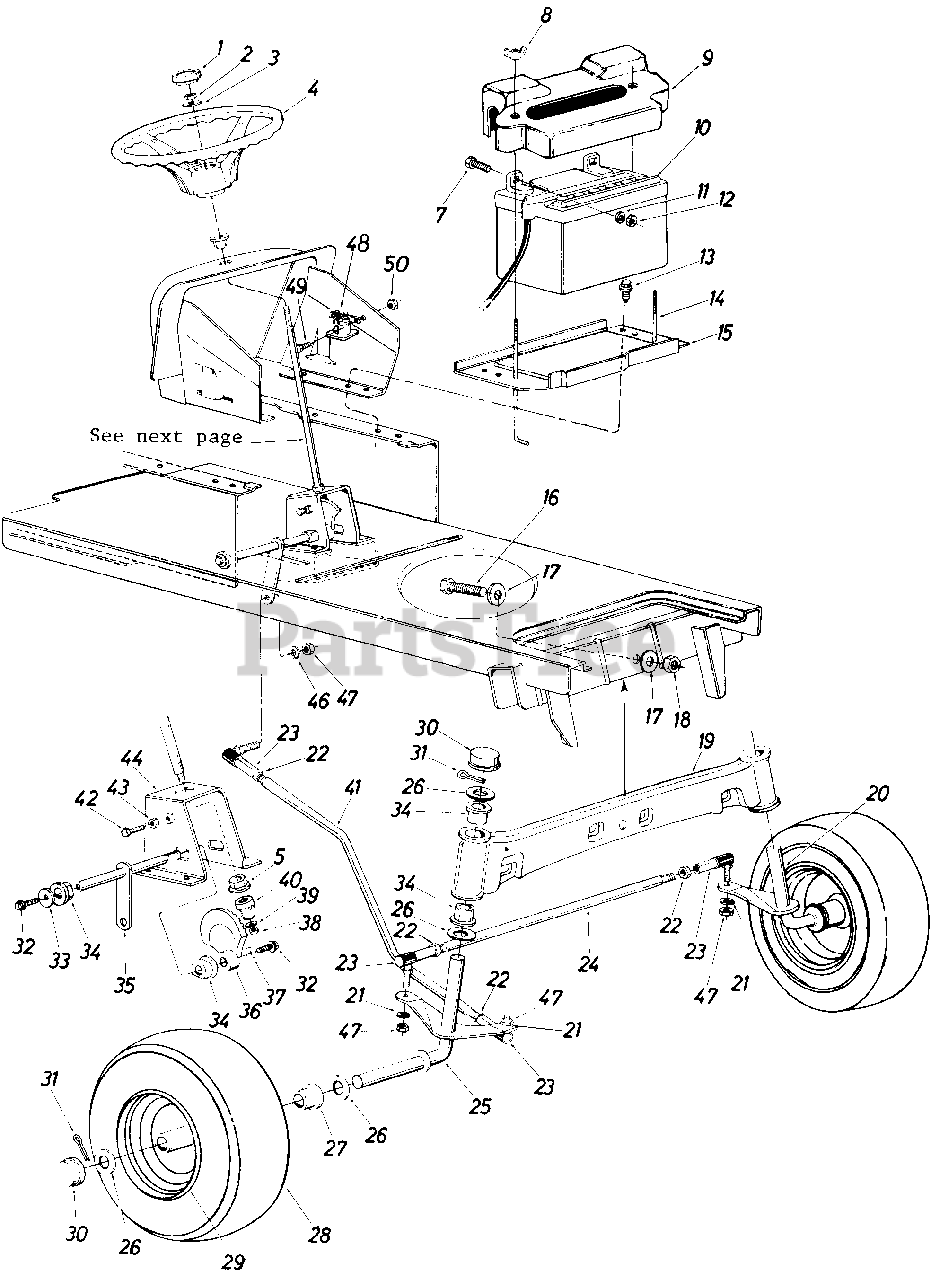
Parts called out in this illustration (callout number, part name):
1	Steering Wheel Cap
2	Hex Cent. L-Nut 5/16-24 Thd.
3	Bell-Wash. 5/16" I.D. x .87" O.D. x .060
4	Steering Wheel
5	Plastic Hex Bearing 5/8" I.D.
5	Steering Column Bearing
7	Hex Bolt 1/4-20 x .62" Lg.
8	Wing Nut Plastic 1/4-20 Thd.
9	Battery Cover
10	32-V Battery
11	L-Wash. 1/4" I.D.
12	Hex Nut 1/4-20 Thd.
13	Hex Thd. Rolling Scr. 1/4-20 x.50" Lg.
14	Battery Hold Down Rod
15	Battery Plate
16	Hex Bolt 5/8-18 x 2.5" Lg.
17	Flat Wash. .66" I.D. x 2.25" O.D. x .17
18	Hex Cent. L-Nut 5/8-18 Thd.
19	Front Pivot Bar Ass'y.
20	Front Axle Ass'y. L. H .
21	L-Wash. 3/8" I.D.
22	Hex Jam Nut 3/8-24 Thd.
23	Ball Joint Ass'y.
24	Tie Rod
25	Front Axle Ass 'y. R . H .
26	Fl-Wash. .780 I.D. x 1.59 O.D.
27	Bearing (16 x 6.50) Turf Tread
28	Wheel Ass'y. Comp. (16 x 6.50) Turf Tread
29	Rim Only (16 x 6.50) Turf Tread
30	Dust Cover
31	Cotter Pin 5/32" Dia. x 1.00" Lg.
32	Hex Bolt 3/8-24 x .75" Lg. Grade 5
33	Fl-Wash. 3/8 I.D. x 1.25 O.D. x .090
34	Flange Double "D" Brg. .753 0 I.D.
35	Steering Arm Shaft Ass'y.
36	Side Gear Steering
37	Bell-Wash. 3/8" I.D.
38	Hex Cent. L-Nut 5/16-24 Thd.
39	Fl-Wash. 5/16" I.D. x .62 0 O.D. x .059
40	Pinion Gear Steering
41	Drag Link
42	Hex Nylon Scr. 3/8-16 x 1.25" Lg.
43	Hex Nut 3/8-16 Thd.
44	Steering Gear Sup. Ass'y.
44	Steering Shaft
46	L-Wash. 3/8" I.D.
47	Hex Nut 3/8-24 Thd.
48	Solenoid
49	Hex Bolt 1/4-20 x .5" Lg.
50	Hex Sems Nut 1/4-20 Thd.
